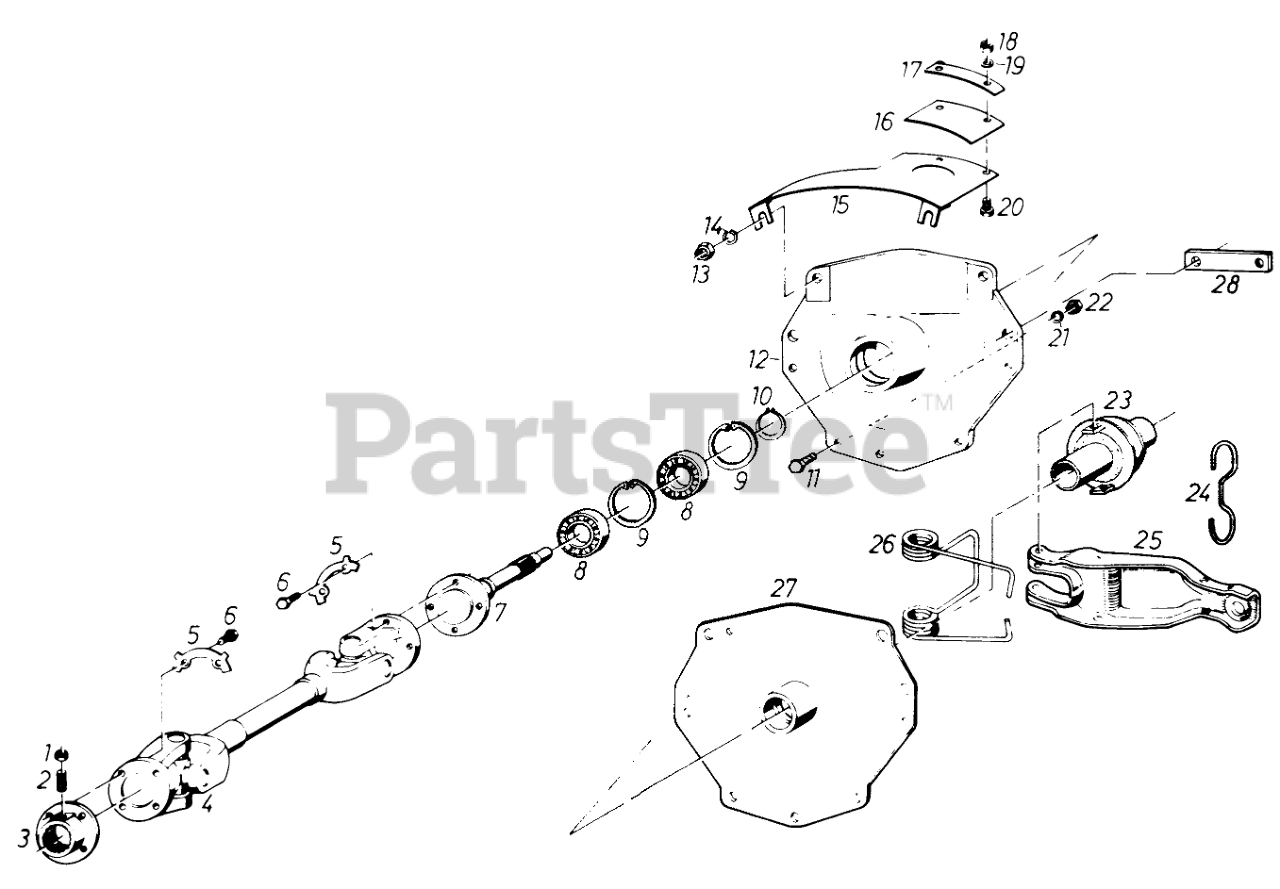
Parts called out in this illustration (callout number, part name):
2	Stud
3	Sliding Flange
4	DRIVE SHAFT
5	Lock Washer
6	Screw
7	Clutch Shaft
8	Ball Bearing
9	Circlip
10	CIRCLIP
12	Flange
14	Washer
15	Protection Assy
16	Rubber Plate
17	Lock Plate
19	Washer
21	Lockwasher
23	Clutch Thrust Ring
24	Spring
26	Spring
27	Clutch Plate
28	Bracket
